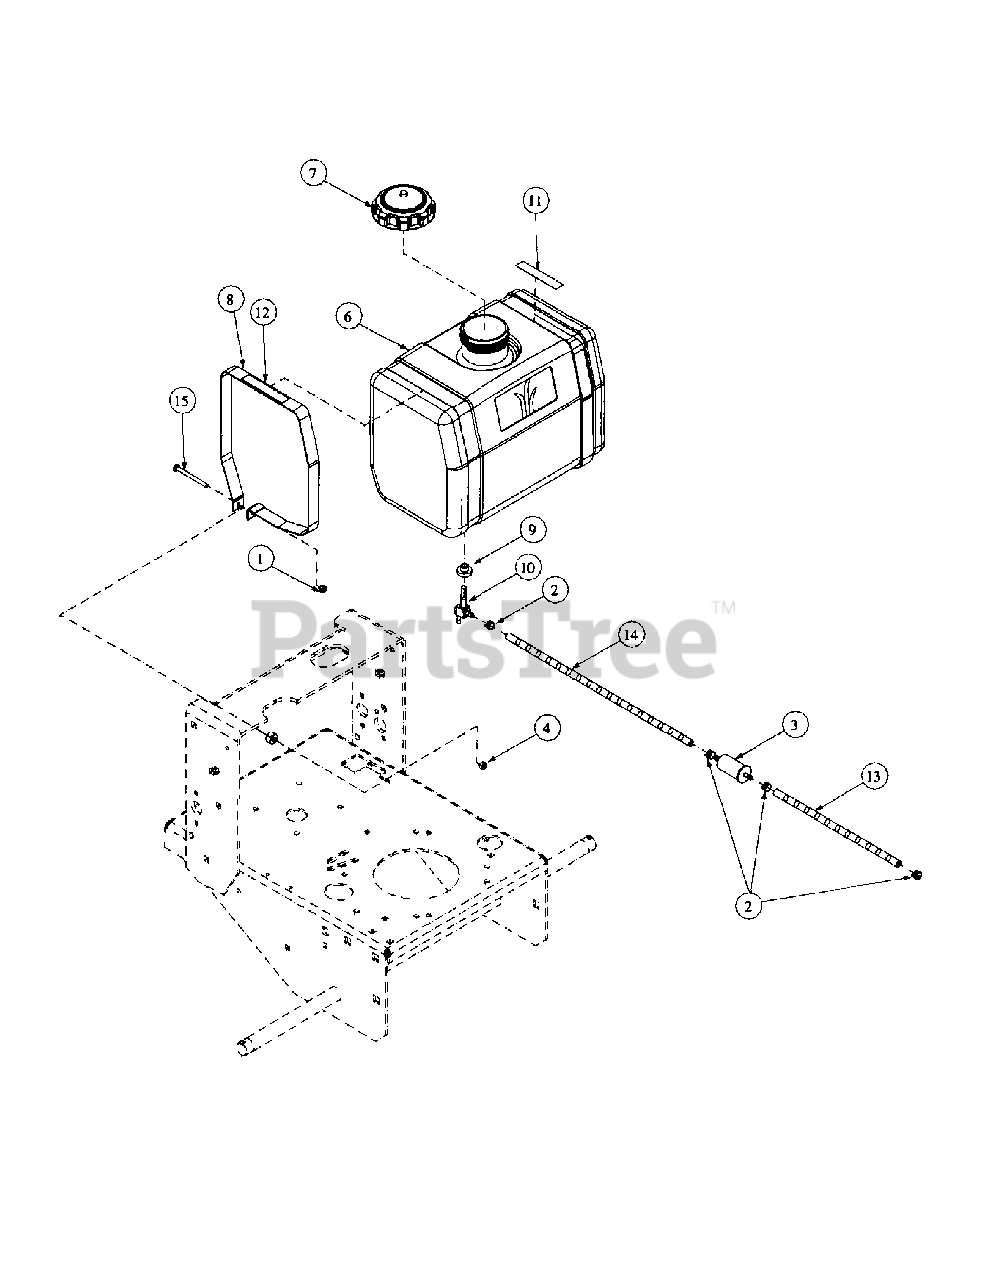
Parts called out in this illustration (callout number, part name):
1	Lock Nut, Nylon Insert, 1/4-20
2	Uni-Clamp
3	Fuel Filter
4	Nut, 1/4-20
5	Rubber Stop Pad
6	Fuel Tank
7	Fuel Cap, 3.5
8	Fuel Tank Strap
9	Grommet Fuel Tank
10	Shut Off Fuel Tank
11	Label, Mower Warning Turn Off Engine
12	Label, Mower Instruction, Fuel Valve
13	Hose Fuel, 12"
14	Hose Fuel, 18"
15	Carriage Bolt, 1/4-20 x 3.00
